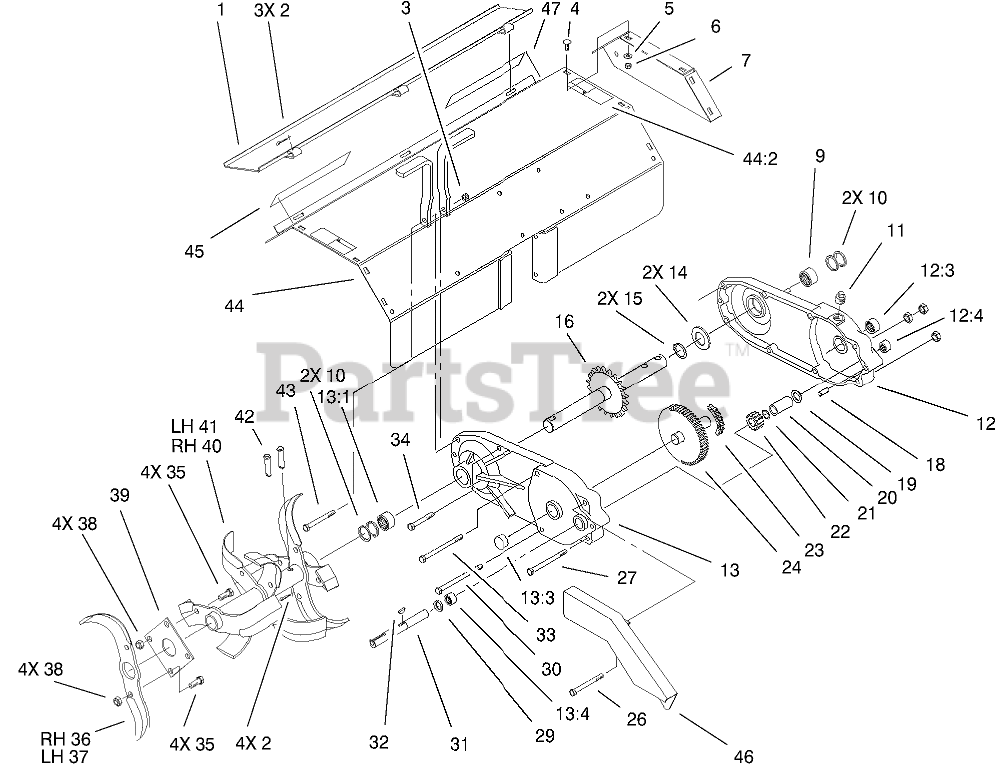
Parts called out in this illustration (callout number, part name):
1	GUARD ASM
2	PIN-COTTER
3	NUT-LOCK, NI
4	BOLT-CARR
5	WASHER-PLAIN
6	NUT-LOCK, NI
7	COVER-TINE END
11	PLUG-PIPE, SQH
12	Gear Case/Bearing ASM-RH
12:1	GEARCASE-TILLER
12:2	BEARING-NEEDLE
12:3	BEARING-NEEDLE
12:4	BEARING-NEEDLE
13	Gear Case/Bearing ASM-LH
13:1	GEARCASE-TILLER
13:2	BEARING-NEEDLE
13:3	BEARING-NEEDLE
13:4	BEARING-NEEDLE
14	WASHER
15	RING-RETAINING
16	TINE SHAFT ASM
18	PIN-ROLL
19	WASHER-THRUST
20	TUBE-SPACER
21	Ring-Snap
22	GEAR-PINION
23	CHAIN
24	GEAR AND SHAFT ASM
26	SCREW-HH
27	SCREW-HH
29	SEAL-OIL
30	SCREW-HH
31	SHAFT-INPUT
32	KEY-WOODRUFF
33	SCREW-HH
34	SCREW-HH
35	SCREW-HH
36	TINE-RH
37	TINE-LH
38	NUT-LOCK, NI
39	PLATE-TINE MOUNTING
40	RH TINE ASM
41	LH TINE ASM
42	PIN-CLEVIS
43	SCREW-HH
44	TINE SHIELD/DECAL ASM
44:2	DECAL-DANGER
45	DECAL-ATTACHMENT
46	GUARD-TILLER
47	DECAL-WORKHORSE
